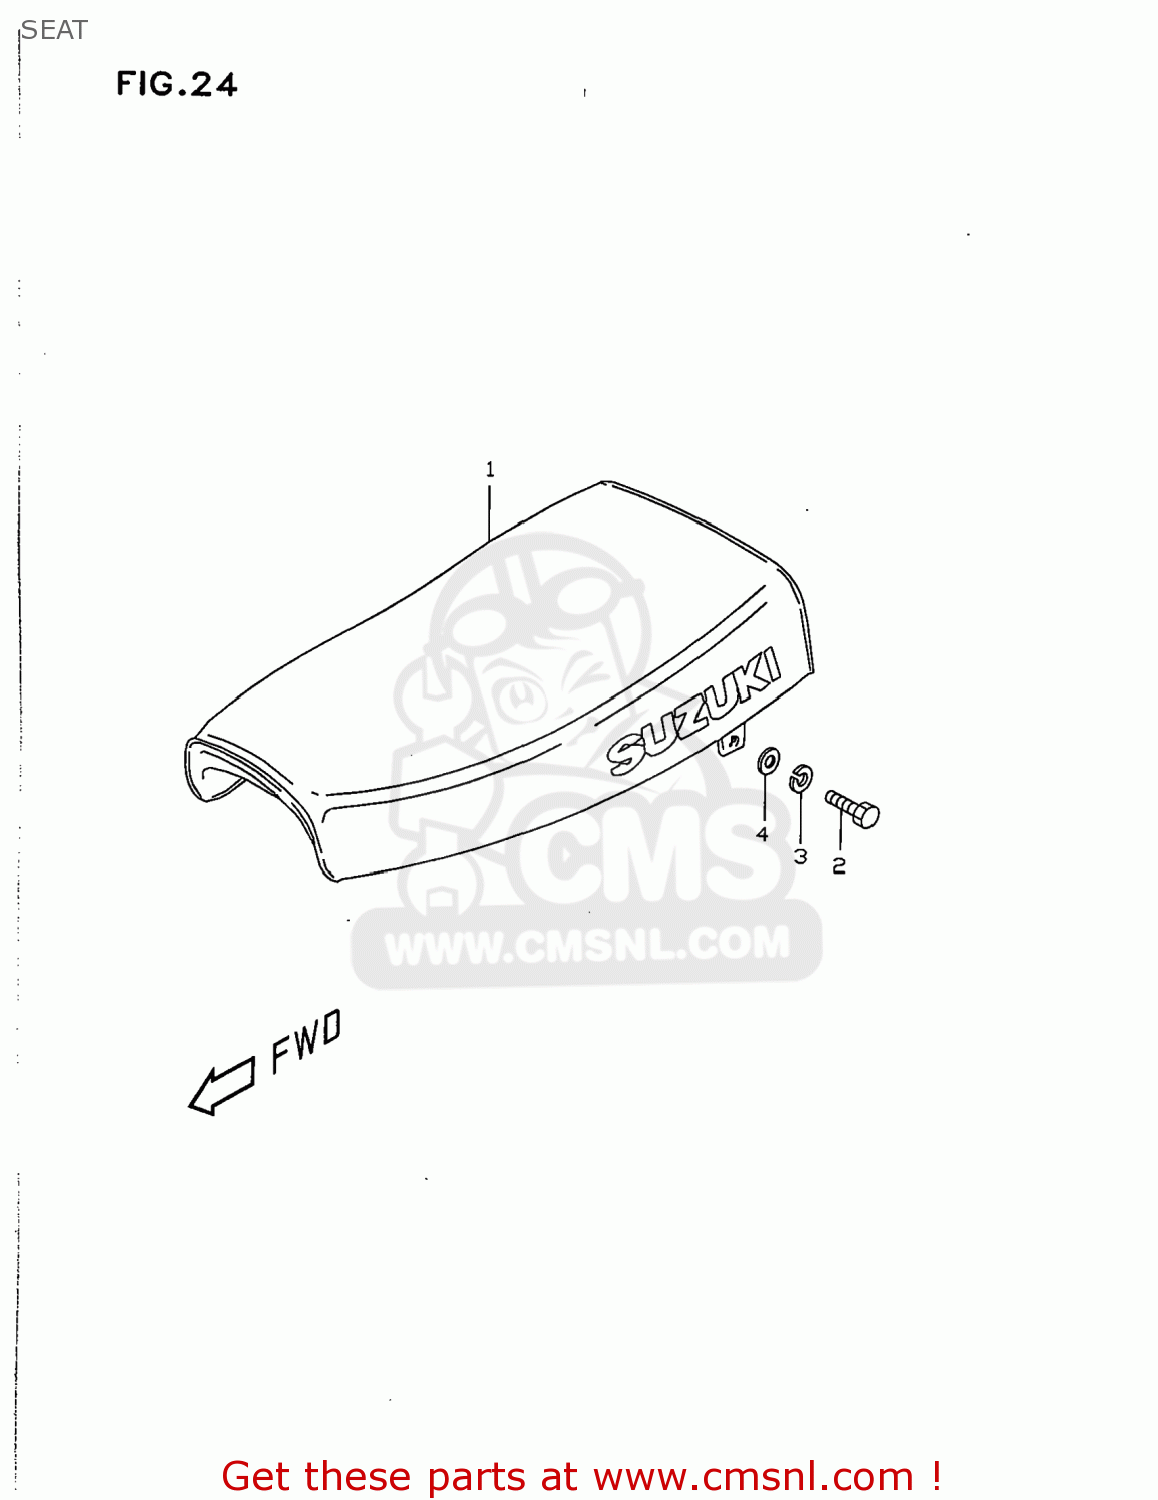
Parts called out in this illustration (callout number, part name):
1	SEAT SET
2	BOLT
3	LOCK WASHER
4	WASHER
